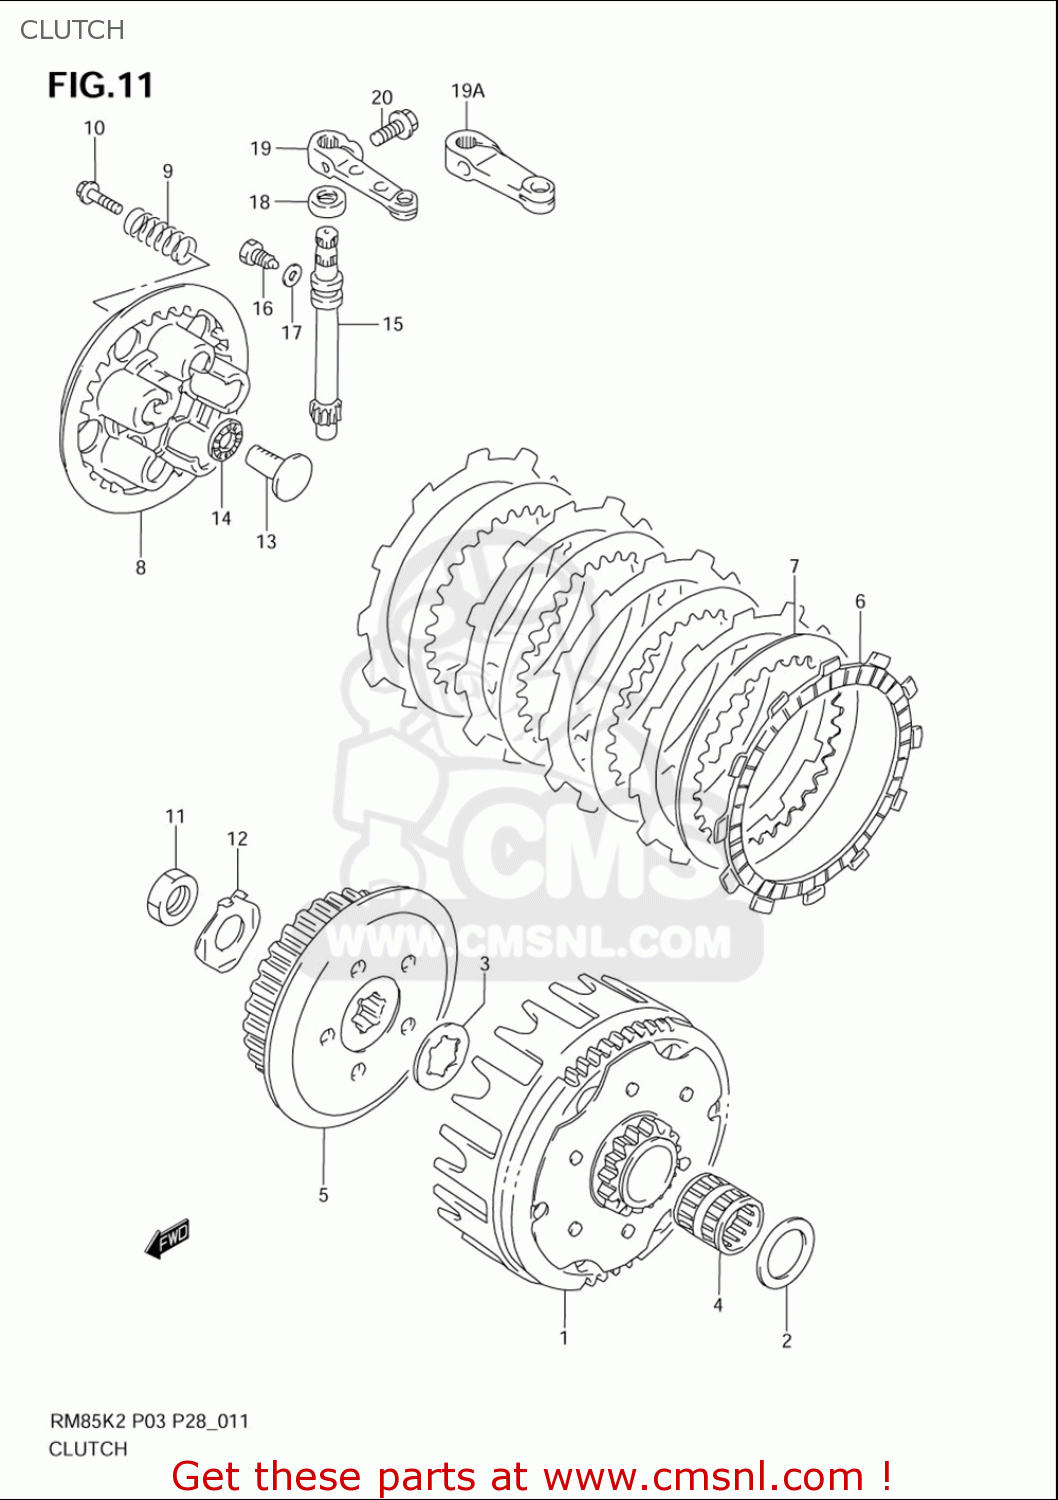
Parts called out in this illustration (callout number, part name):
1	GEAR ASSY,PRI DRIVEN(NT:62/16)
2	SHIM(20X32X1)
3	WASHER,LOCK
4	BEARING(20X25X26)
5	HUB,CLUTCH SLEEVE
6	PLATE,CLUTCH DRIVE(T:3.0) (NAS)
7	PLATE,CLUTCH DRIVEN(T:2.0) (NAS)
8	DISC,CLUTCH PRESSURE
9	SPRING
10	BOLT(5X16)
11	NUT
12	WASHER
13	RACK,CLUTCH RELEASE
14	BEARING(10X22X2.8)
15	PINION,CLUTCH RELEASE
16	BOLT(6X10)
17	GASKET(6.2X11X1).2 (NAS)
18	SEAL,OIL(10X17X5)
19	ARM,CLUTCH RELEASE
19A	ARM,CLUTCH RELEASE
20	BOLT(6X16)
